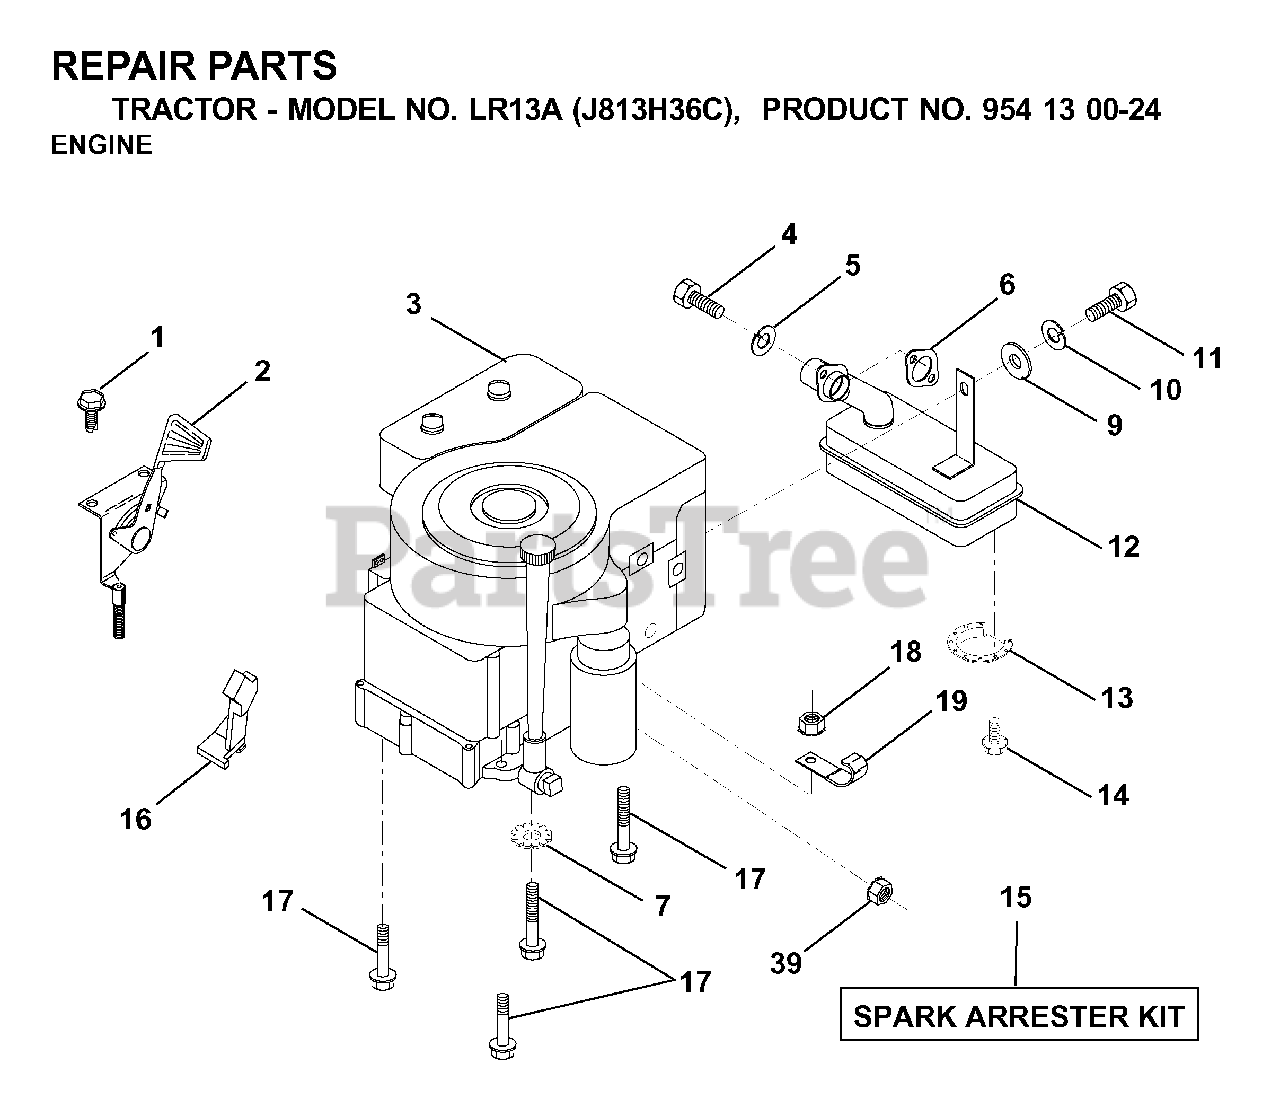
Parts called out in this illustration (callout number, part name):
1	SCREW LT
2	THROTTLE CONTROL
4	SCREW
5	LOCKWASHER
6	REPL BY 532 27 22-93
7	LOCKWASHER
9	WASHER
10	LOCKWASHER
13	DEFL MUFFLER LTV
14	SCREW
15	ARRESTER SPARK (OPTIONAL)
16	STOP THROTTLE
17	SCREW LT
19	CLIP T
39	NUT FLANGE 1/4-20 STARTER NUT
